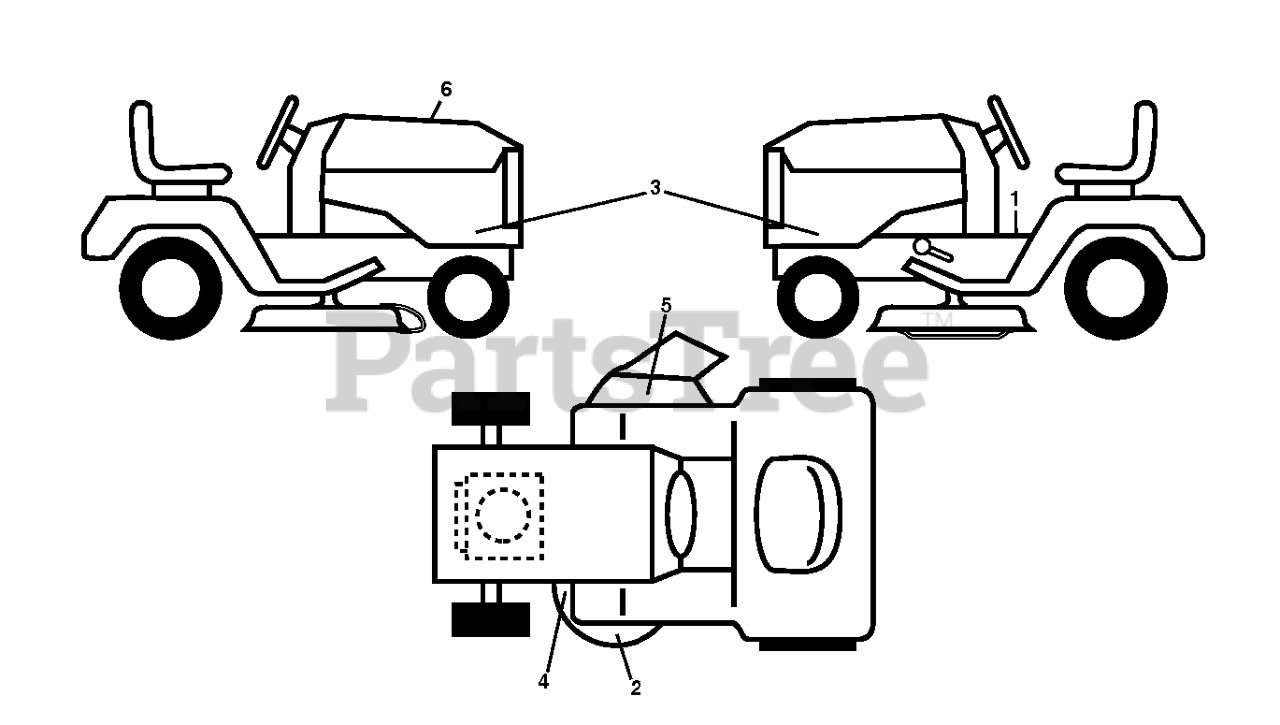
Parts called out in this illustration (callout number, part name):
1	DECAL.WARNING.2007.ENG/FR
2	DECAL.DECK.STAMP.BIOCLIPCMP.HU
4	DECAL.V-BELT.SCH.42/46"MEC/ELE
5	DECAL, DECK DEFLECTOR, WARNING
